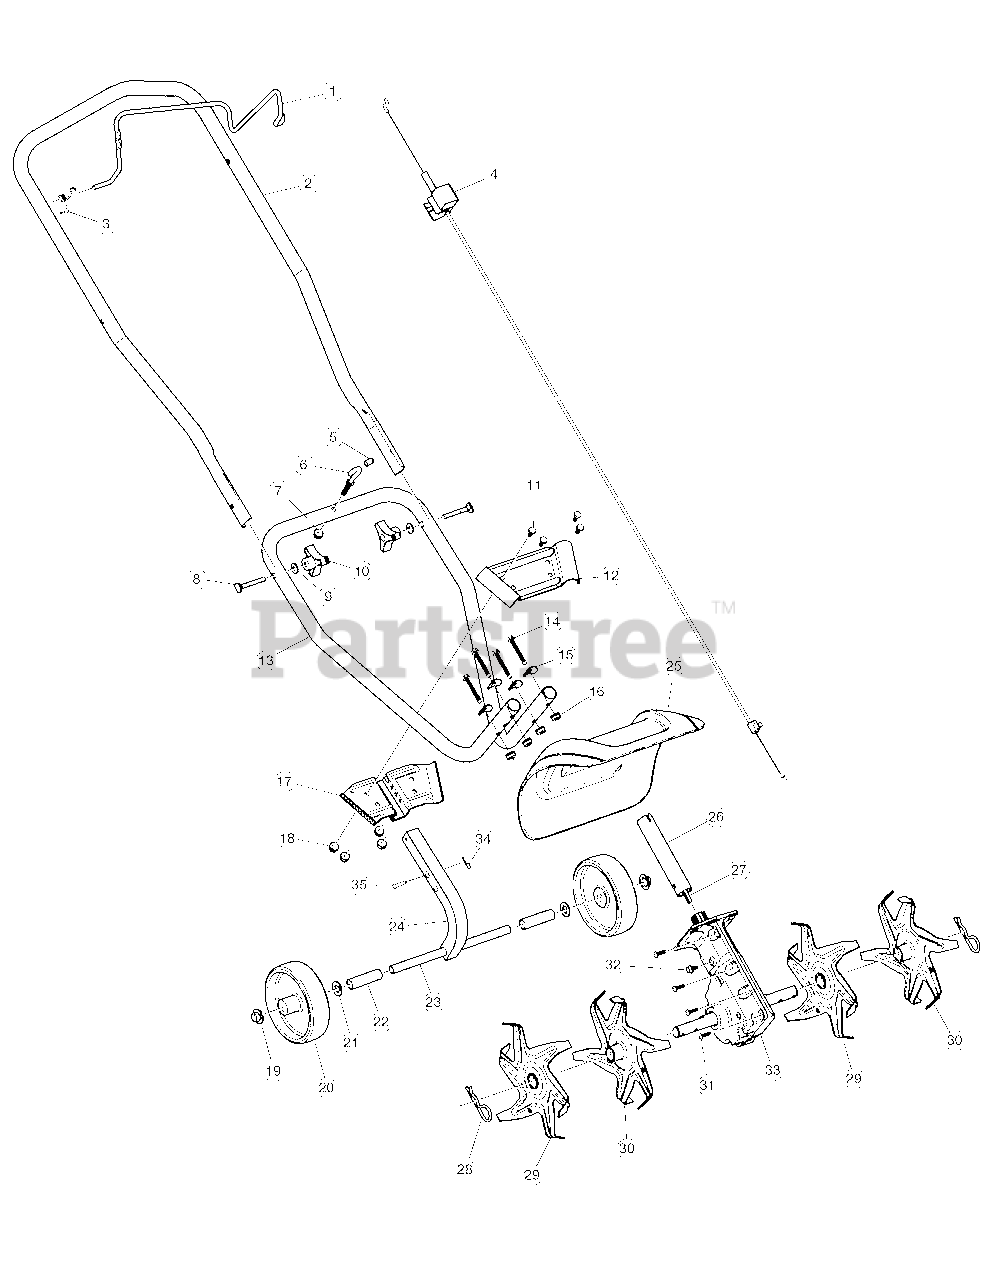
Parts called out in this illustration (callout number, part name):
1	Throttle
2	Handle
3	Spring
4	Throttle Cable
5	Cap
6	Eyelet Bolt
7	Nut
9	Washer
12	Bracket, Upper
13	Handle
14	Bolt
15	Washer
16	Nut
17	Bracket, Lower
18	Nut
19	Cap
20	Wheel (Incl. 19)
22	Spacer
24	Tube, Square
25	Shield
26	Tube (Incl. 27)
27	Flex Shaft
29	Tine (Left Inner, Right Outer)
30	Tine (Left Outer, Right Inner)
32	Screw
33	Gearbox (Incl. 31)
34	Cotter Pin
35	Clevis Pin
